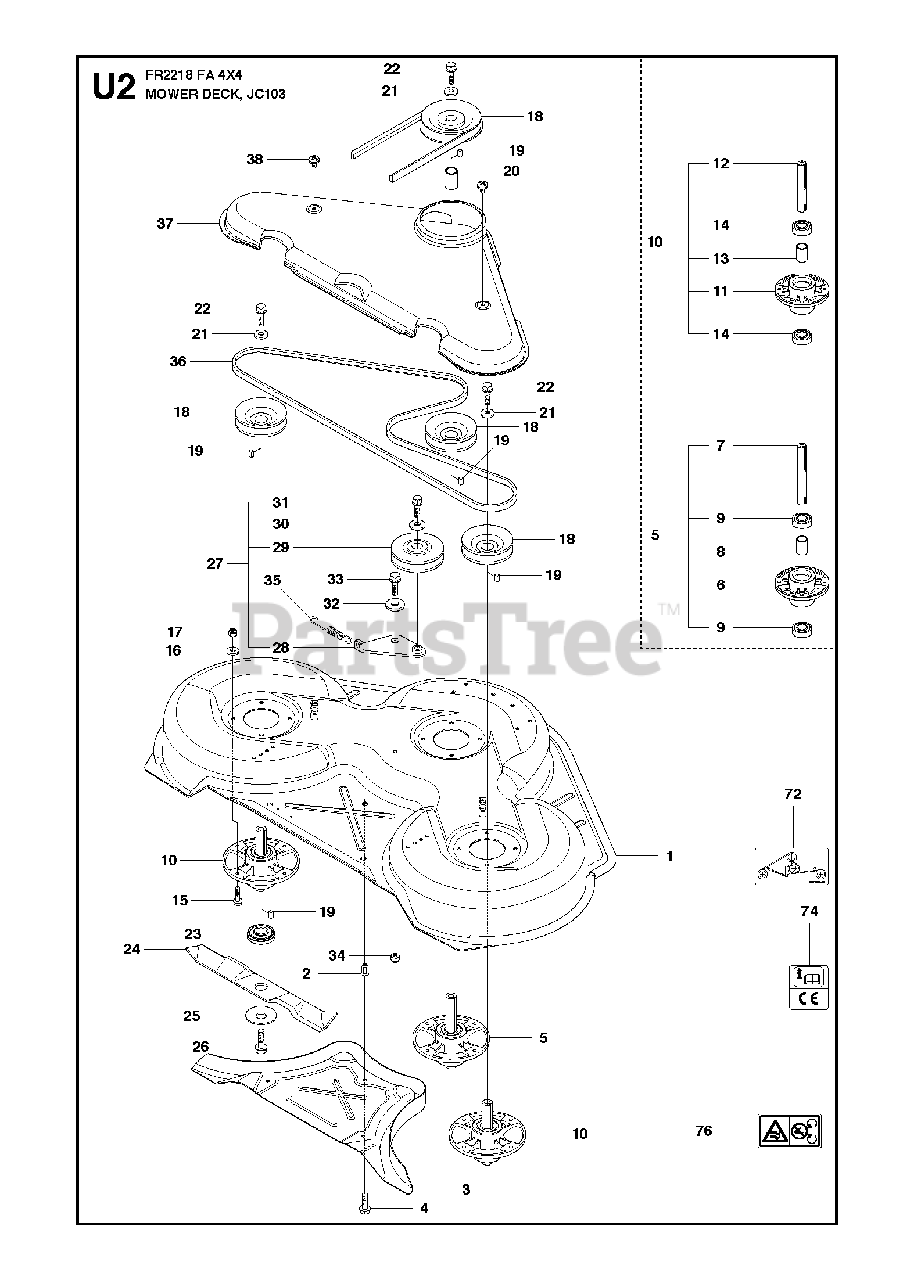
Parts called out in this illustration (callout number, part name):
5	BLADE HOUSING ASSY
6	BEARING HOUSING
7	SHAFT
8	SPACING SLEEVE
9	BEARING
10	BLADE HOUSING ASSY
11	BEARING HOUSING
12	SHAFT
13	SPACING SLEEVE
14	BEARING
16	WASHER BRB 8.4X17
17	LOCKNUT M8
24	BLADE
27	BELT TENSIONER ASSY
28	BELT TENSIONING ARM
29	PULLEY
30	SPACER
31	BOLT
32	WASHER
34	LOCKNUT M8
36	BELT
